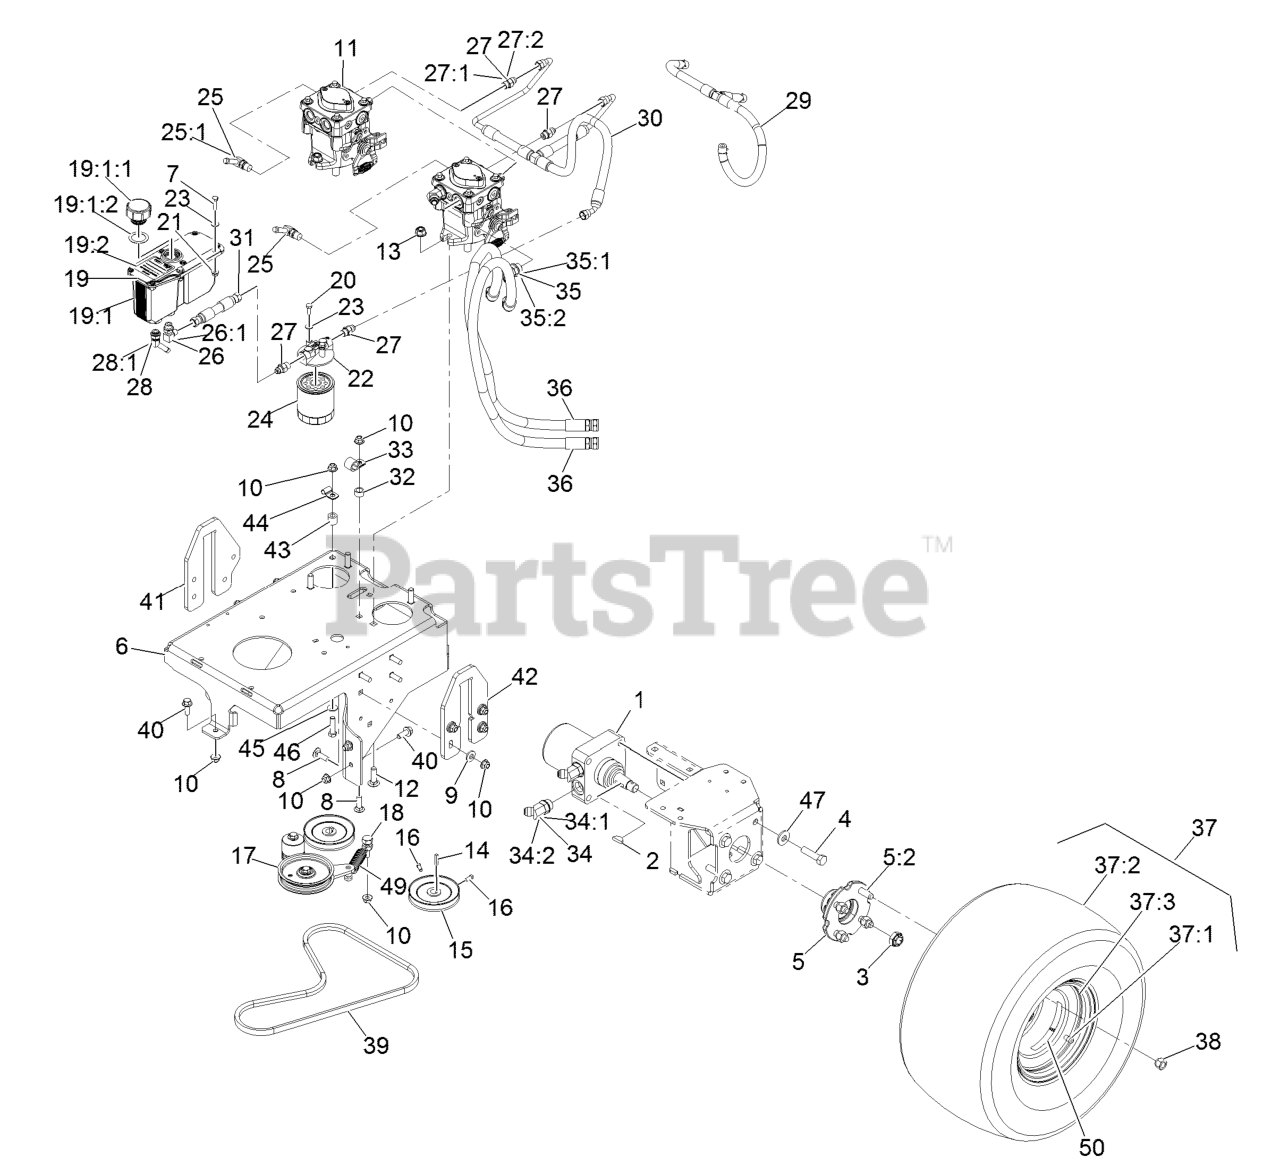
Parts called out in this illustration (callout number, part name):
1	MOTOR-WHEEL
2	KEY-WOODRUFF
3	NUT-LOCK
4	SCREW-HH
5	WHEEL HUB ASM
5:2	STUD-TYPE, DRIVE
6	BASE, ENGINE
7	SCREW-HH
8	BOLT-CARR
9	WASHER-BELLEVILLE
10	NUT-HF, NI
11	PUMP - HYDRAULIC
12	SCREW-HH
13	NUT-HF, NI
15	PULLEY-PUMP
16	SCREW-SET
17	PUMP IDLER ASM
18	ANCHOR, SPRING
19	RESERVOIR ASM
19:1	Reservoir-Hyd
19:1:1	Cap-Reservoir, HYD
19:1:2	GASKET-CAP
19:2	DECAL-HYDRAULIC TANK
20	SCREW-HH
21	NUT-HHF
22	HEAD-FILTER
23	WASHER-FLAT
24	FILTER-25 MICRON, BI-DIRE
25	FITTING-ELBOW, 90
25:1	O-RING
26	FITTING-ELBOW, 90 DEG
27	FITTING-STRAIGHT
28	FITTING-BARBED, 45 DEG
28:1	O-RING
29	TANK HOSE ASM
30	HOSE ASSEMBLY - CHARGE
31	HYD HOSE ASM
32	SPACER-WHEEL
33	CLIP-LOOM
34	FITTING-HYD, 45 DEG
35	FITTING-HYD, 45 DEG
36	HYD HOSE ASM
37	WHEEL/TIRE ASM
37:1	RIM-8 INCH
37:3	Stem-Valve
38	NUT-LUG
39	BELT-V, LOWER PTO
40	SCREW-HHF 3/8-16 X 1
41	PLATE-LIFT, RH
42	PLATE, LIFT LH
44	CLIP-TUBE
45	WASHER-FLAT
46	SCREW-HH
47	WASHER-SPRING
49	SPRING-EXTENSION
